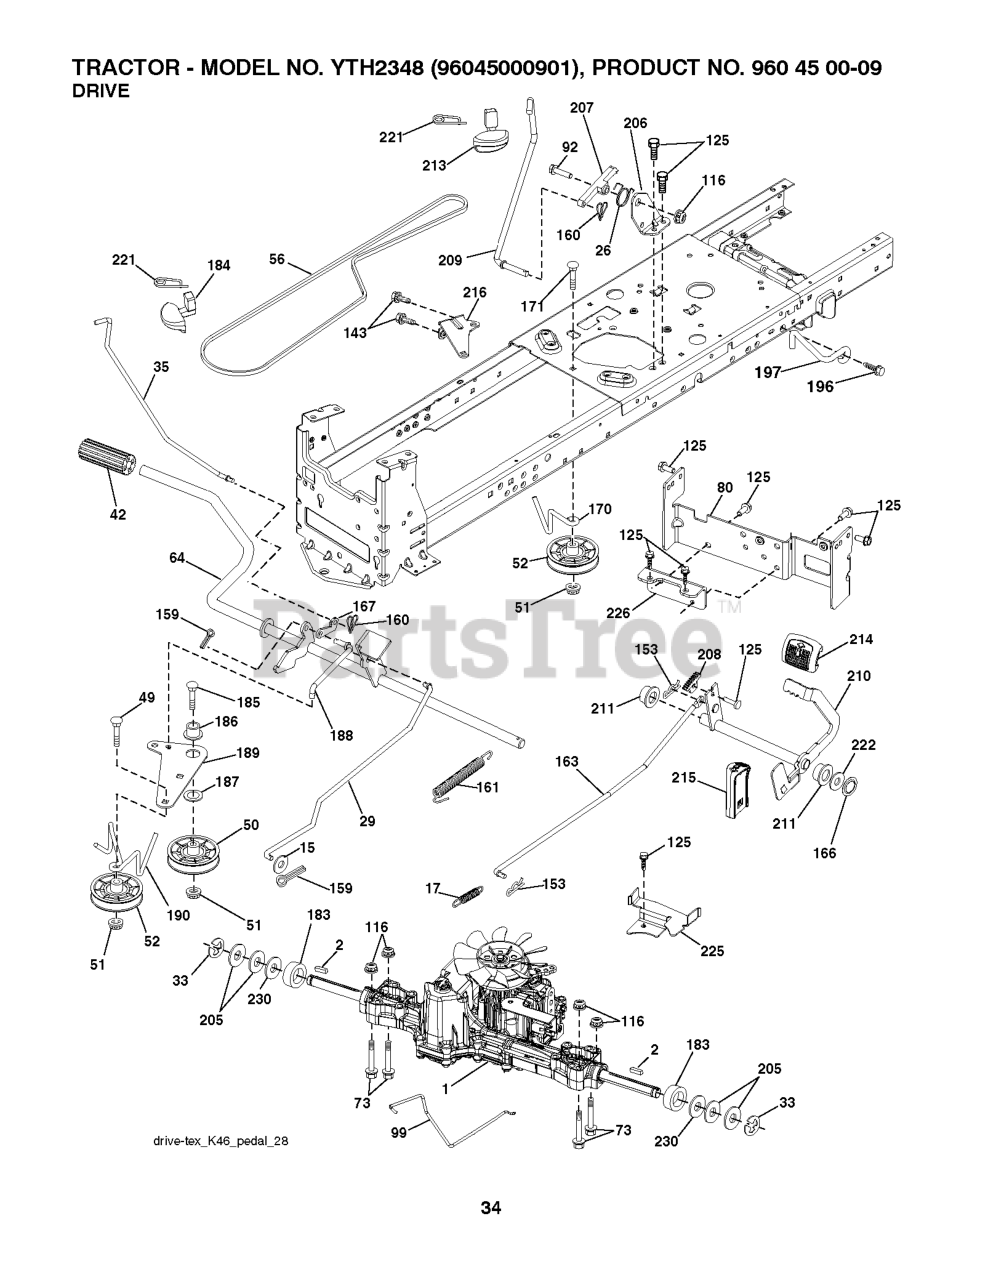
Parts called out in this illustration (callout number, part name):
1	TRANSAXLE, TUFFTORQ K46
2	SQUARE KEY
15	WASHER
17	SPRING.BRAKE.K46.GREEN
26	SPRING.RETURN.CRUISE
29	ROD.BRAKE.K46
35	ROD.BRAKE.PARKING.GT.H
42	PEDAL COVER T
50	IDLER.FLAT.910.OFFSET
51	NUT LOCK FLG 3/8-16 UNC
52	IDLER.V-GROOVE.910.OFFSET
56	V-BELT.MOWER.92.40.42/K46
64	SHAFT.ASM.PEDAL.BRK.CNTR
73	BOLT HEX 5/16-18 GR 5
80	STRAP TORQUE.ASM.K46/18"TEX
92	BOLT
99	ROD.SPRING.BYPASS.K46.LT.Z
116	NUT LOCK HEX FLANGE 5/16-18
125	SCREW
143	Screw 5/16-18 x 1/2 Hex, Self Tapping 5/16-18 x 1/2
153	RETAINER M
159	COTTER PIN
160	RETAINER CLIP
161	SPRING, RETURN LT
163	ROD.CONTROL.PEDAL.K46
166	NUT.PUSH.625.2006
167	LATCH.BRAKE.SPRING
170	KEEPER.V-IDLER.CENTER.
183	SPACER AXLE
184	HANDLE.PARKG.BRK.HUSQ X667
186	SPACER.RETAINER
187	WASHER 12/32X2X10GA
188	RP.LINK.CLUTCH.GROUND.DRIVE
189	BELLCRANK.GROUND.DRIVE.TEX.
190	KEEPER.BELLCRANK.DRIVE
196	SCREW 3/8-16X1
197	LINK.CLUTCH.ANIT-ROTAT
206	BRKT.MOUNT.LATCH.CRUIS
207	LATCH.CONTROL.CRUISE
208	GEAR.SECTOR.CONTROL.CR
209	ROD.CONTROL.CRUISE.GT.
210	ROCKER.ASM.PEDAL.CONTR
211	BEARING.NYLON
213	KNOB.CONTROL.CRUSIE.HU
214	PEDAL.FORWARD.TEX.GT.4
215	PEDAL.REVERSE.TEX.GT.4
216	BRACKET.PULLEY.IDLER.W/TEX
221	RETAINER.SPRING.CLIP.H
222	WASHER 21/32 X 1-1/4 X 10 GA.
225	KEEPER.BELT.TRANSAXLE.K46
226	BRACKET.MOUNT.TORQUE.K46.TLT
230	WASHER.HARDENED
